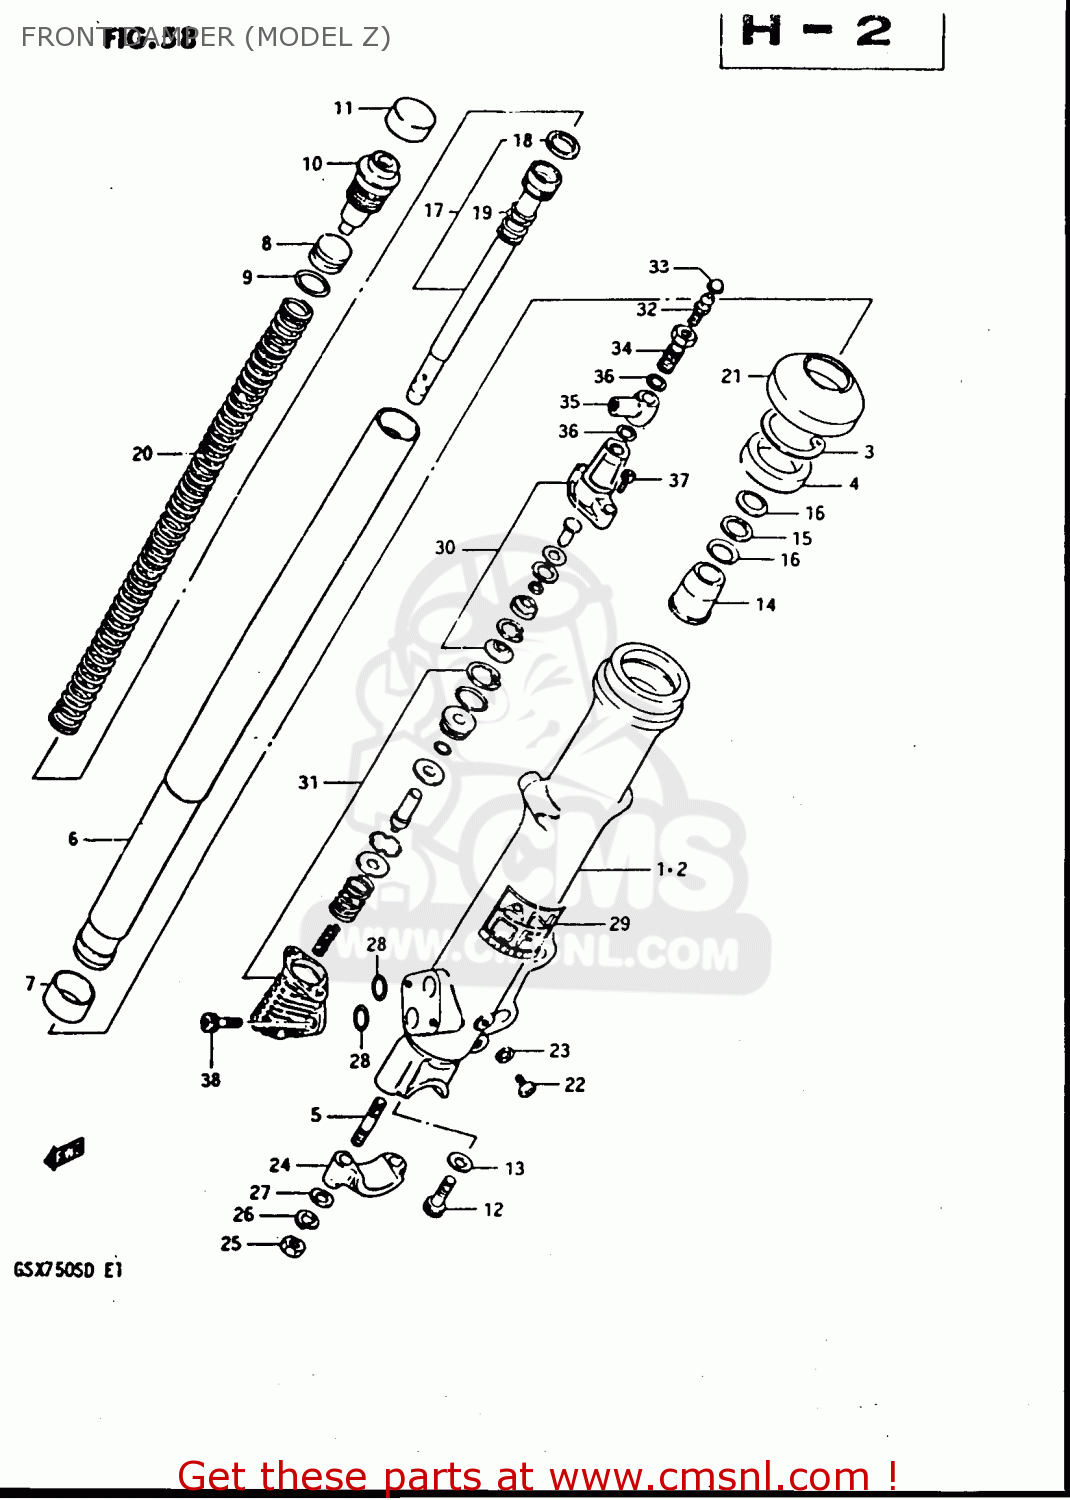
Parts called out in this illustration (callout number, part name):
1	OUTER TUBE, RH
2	OUTER TUBE, LH
3	RING,STOPPER
4	OIL SEAL,FRONT FORK
5	STUD 8X30
6	TUBE,INNER
7	PISTON
8	PISTON,FREE
9	O-RING
10	CAP
11	CAP,RUBBER
12	BOLT,FORK CYLINDER(10X25)
13	GASKET (NAS)
14	PIECE,OIL LOCK
15	WASHER
16	SPRING,LEAF
17	CYLINDER,FRONT FORK
18	RING,PISTON
19	SPRING,REBOUND
20	SPRING,FRONT FORK
21	SEAL,DUST
22	SCREW
23	GASKET,DRAIN,PLUG (NAS)
24	HOLDER,AXLE
25	NUT (8MM)
26	LOCK WASHER
27	WASHER
28	O RING
29	LABEL
30	MODULATOR PARTS SET,FRONT
31	VALVE SET,MODULATOR
32	BREATHER,AIR
33	CAP,BREADER
34	BOLT,UNION
35	SPACER,FRONT FORK MODULATOR
36	WASHER
37	BOLT,FR FORK
38	BOLT,FRONT FORK
